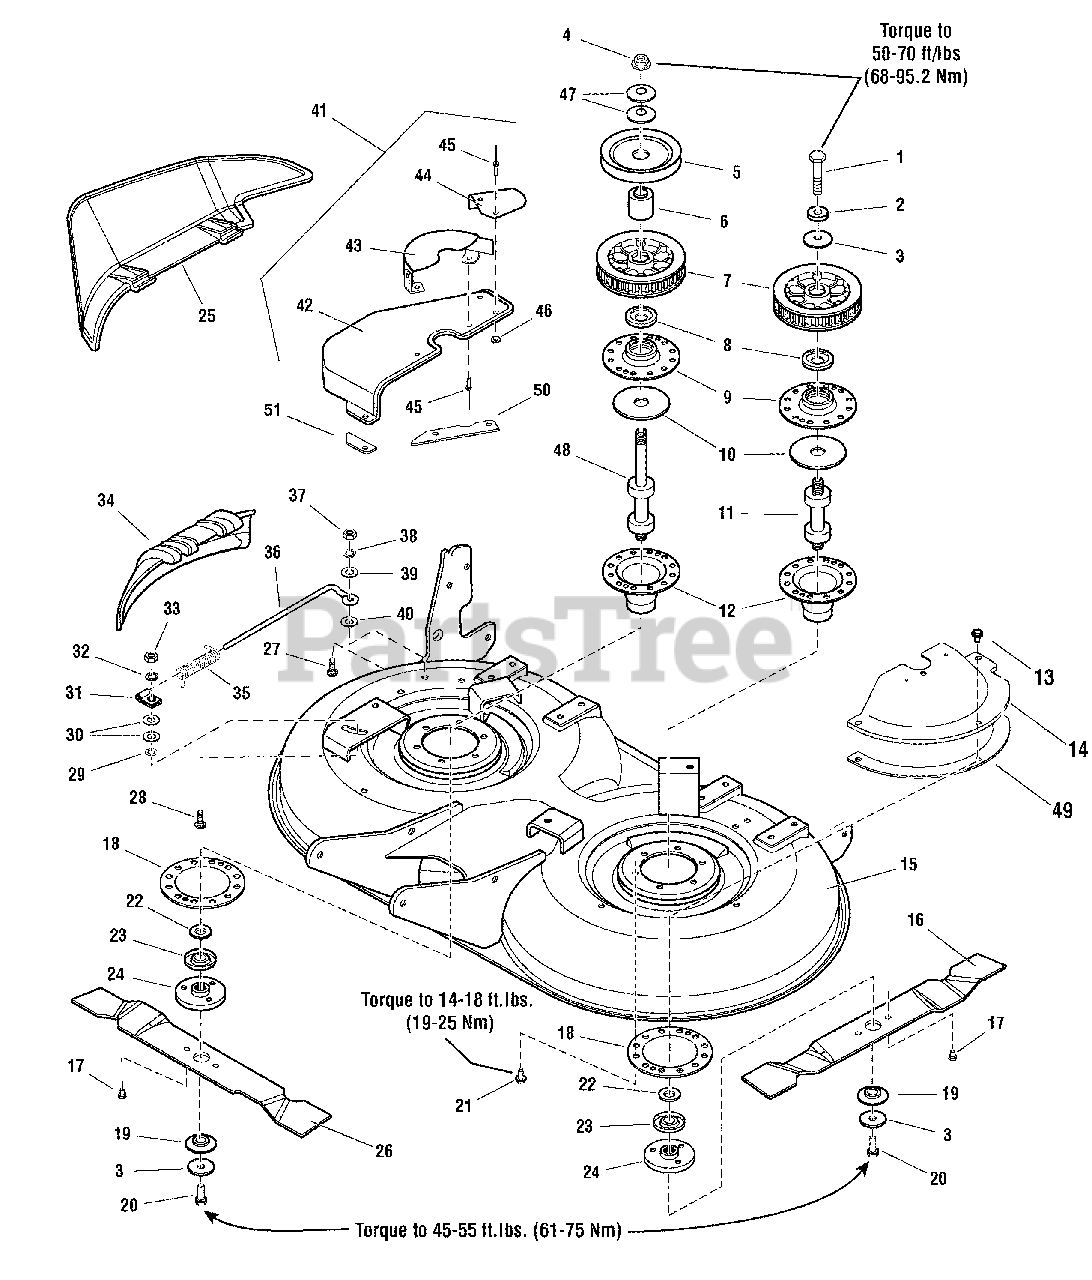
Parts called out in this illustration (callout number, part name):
1	CAPSCREW, Hex Head, 7/16-14 x 2-3/4 G8
2	WASHER, 7/16
3	WASHER, Spring
4	NUT, Hex Flange, 9/16-18
7	SPROCKET & FLANGE ASMY-Rivets/Screws 40"
8	SHIELD, Bearing Upper, Arbor
9	HOUSING, Arbor Top
10	GASKET, Foam Poly
11	ARBOR SHAFT & BEARINGS ASSEMBLY
12	HOUSING, Arbor Bottom with Lube Fitting
13	CAPSCREW, Taptite Hex Washer Head, w/CA Point, 5/16-18 x 3/4
14	COVER, Arbor, LH
15	HOUSING ASSEMBLY, 40", Orange
15	HOUSING ASSEMBLY, 40", Red
16	BLADE, Mower, LH
18	ADAPTOR, Arbor
19	WASHER, Spline
20	CAPSCREW, Hex Head, 7/16-14 x 2-1/4 G8
21	CAPSCREW, Taptite Hex Washer Head, 5/16-18 x 1
22	WASHER, Shim
23	SHIELD, Arbor Bearing, Lower
24	ADAPTER, Blade
25	DEFLECTOR, Discharge
26	BLADE, Mower, RH
27	CARRIAGE BOLT, 5/16-18 x 1
28	CARRIAGE BOLT, 1/4-20 x 7/8
29	NUT, Push
30	WASHER, 1/4
32	LOCKWASHER, Spring 1/4
33	NUT, Hex 1/4-20
34	DOOR, Mulching, Black Plastic
35	SPRING, Torsion
37	NUT, Hex 5/16-18
38	LOCKWASHER, Spring 5/16
39	WASHER, 5/16
40	NUT, Push
41	COVER ASSEMBLY, Arbor, RH (Includes Ref. Nos. 42 thru 46)
42	COVER, Arbor RH
43	GUARD ASSEMBLY, RH
44	GUARD, Extension
46	WASHER, 3/16 x 3/4 x 1/16
47	WASHER, Bellville
48	ARBOR SHAFT & BEARING ASSEMBL
49	SHIM-Cover LH 7GA 40" Mowers Plain
50	SHIM-Cover RH 7GA 6.5 LG 40" Mowers Plain
51	SHIM-Cover RH 7GA 2.8 LG 40" Mowers Plain
